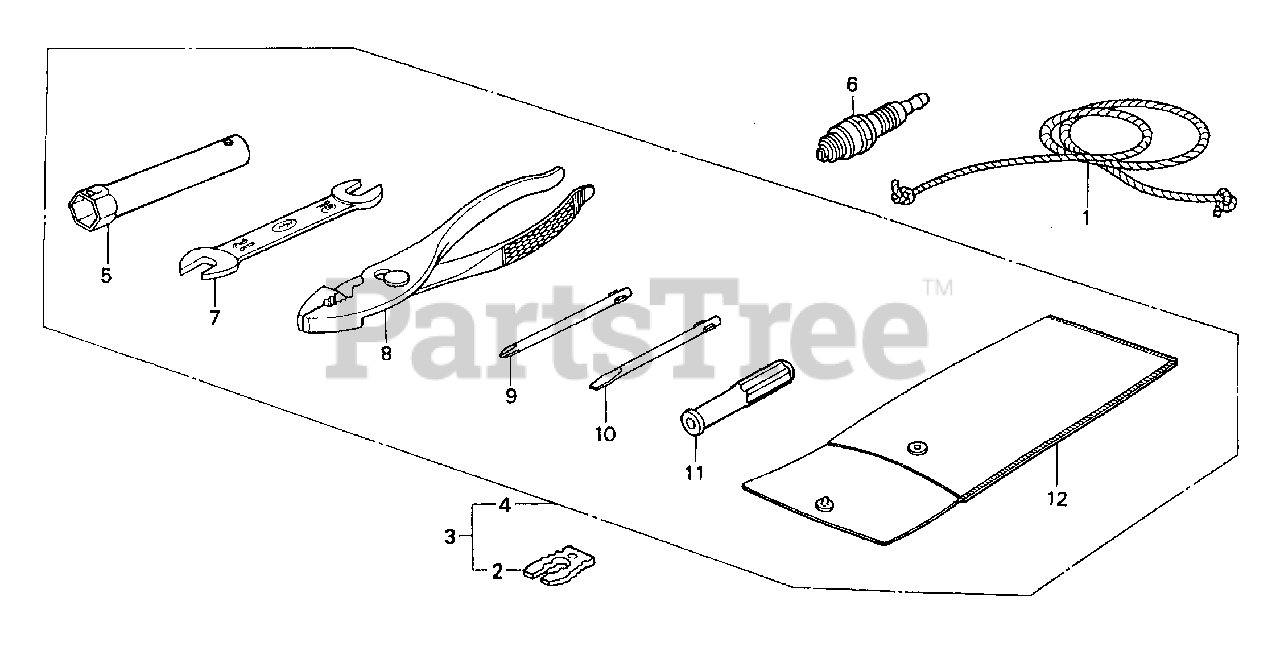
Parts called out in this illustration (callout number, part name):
1	ROPE, STARTER (#4X65") (N/A: USE ALTERNATE P/N 08540-ZG921-11)
2	CLIP, EMERGENCY LOCK
6	SPARK PLUG (BMR4A) (NGK)
